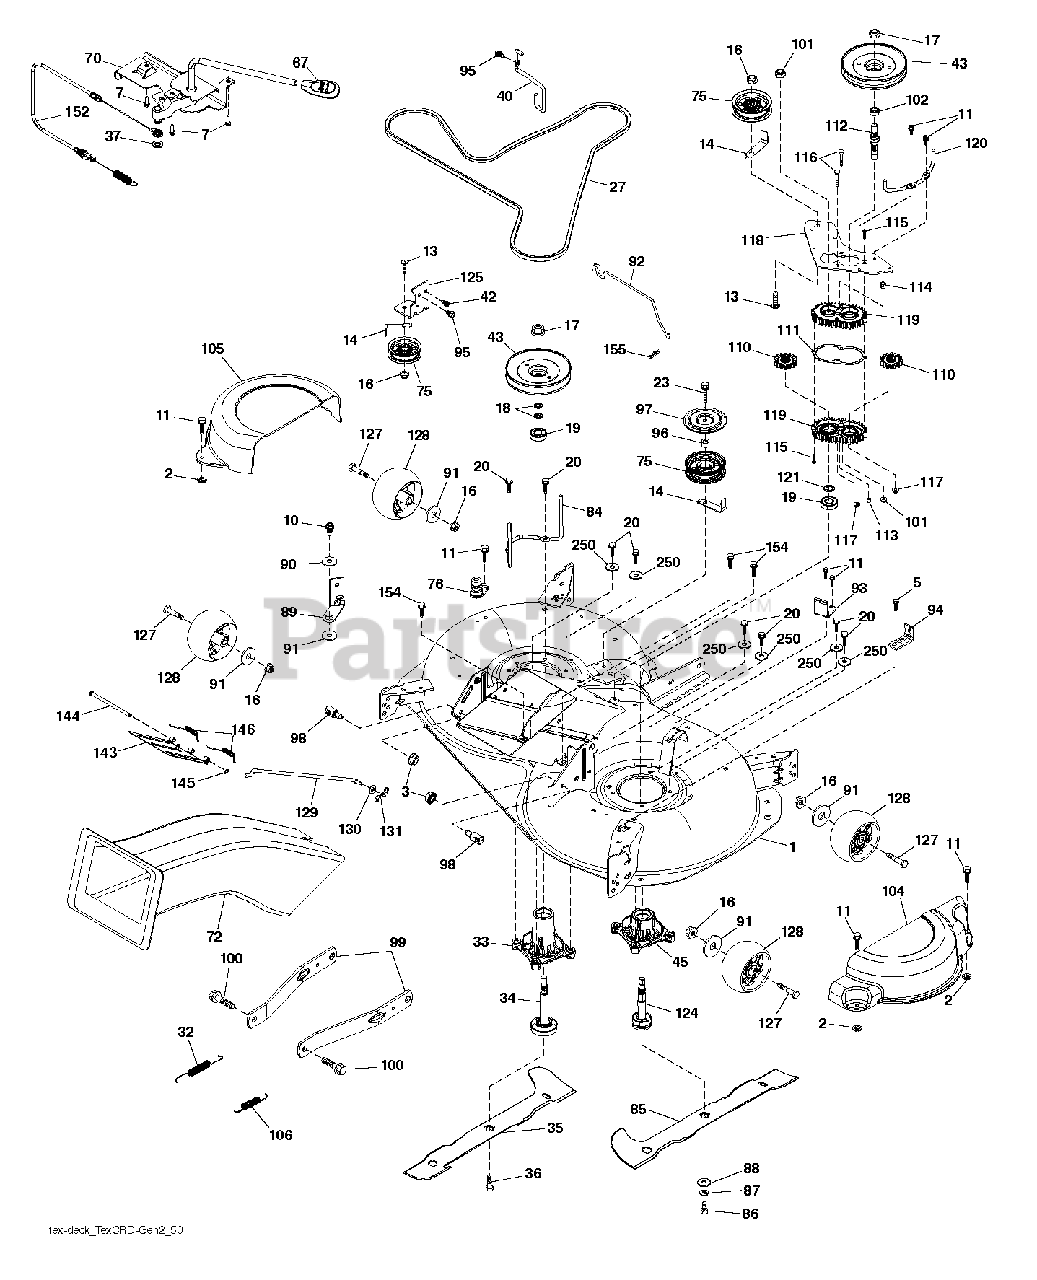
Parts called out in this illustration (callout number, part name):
2	PALNUT 1/4
3	NUT LOCK HEX FLANGE 5/16-18
5	BOLT.5/16HEX.WHS.HD
7	SCREW.#10 X 0.750.BOS THREAD
10	SCREW 3/8-16X1
11	SCREW.1/4-20X5/8
13	BOLT.3/8-16X1.50
14	KEEPER, BELT IDLER
16	NUT LOCK FLG 3/8-16 UNC
17	NUT.FLANGE.LOCK.TOP
18	WASHER.SPACER.MANDREL
20	SCREW, WASHER HEAD
23	SCREW LT
32	SPRING RETURN
36	BOLT.WASHER.ASM.7/16-2
40	KEEPER BELT ENGINE LH
42	SCREW
67	HANDLE.CLUTCH.CABLE.LT
70	CLUTCH.ASM.MANUAL.YT.PREDATORQ
72	CHUTE 10797 TEX GEN
75	FLAT IDLER PULLEY
76	PORT.WASHOUT
87	LOCKWASHER
88	WASHER.BLADE
89	ARM BRAKE MOWER
90	SPACER.RETAINER
94	BRKT.CLUTCH.CABLE
95	SCREW, 3/8-16X3/4
98	STUD.FASTNER.W/ANTI-ROTATE
99	ARM.SUSPENSION.MOWER.R
100	BOLT.SHOULDER
102	SPACER BEARING
106	SPRING.BRAKE.RETURN.38"
117	NUT T
127	BOLT.SHOULDER.3/8-16X3-5/8
128	WHEEL. GUAGE RALLY
130	WASHER
131	PIN.COTTER.5/16.BOW TI
145	E-RING.5/16"
155	RETAINER M
250	WASHER
